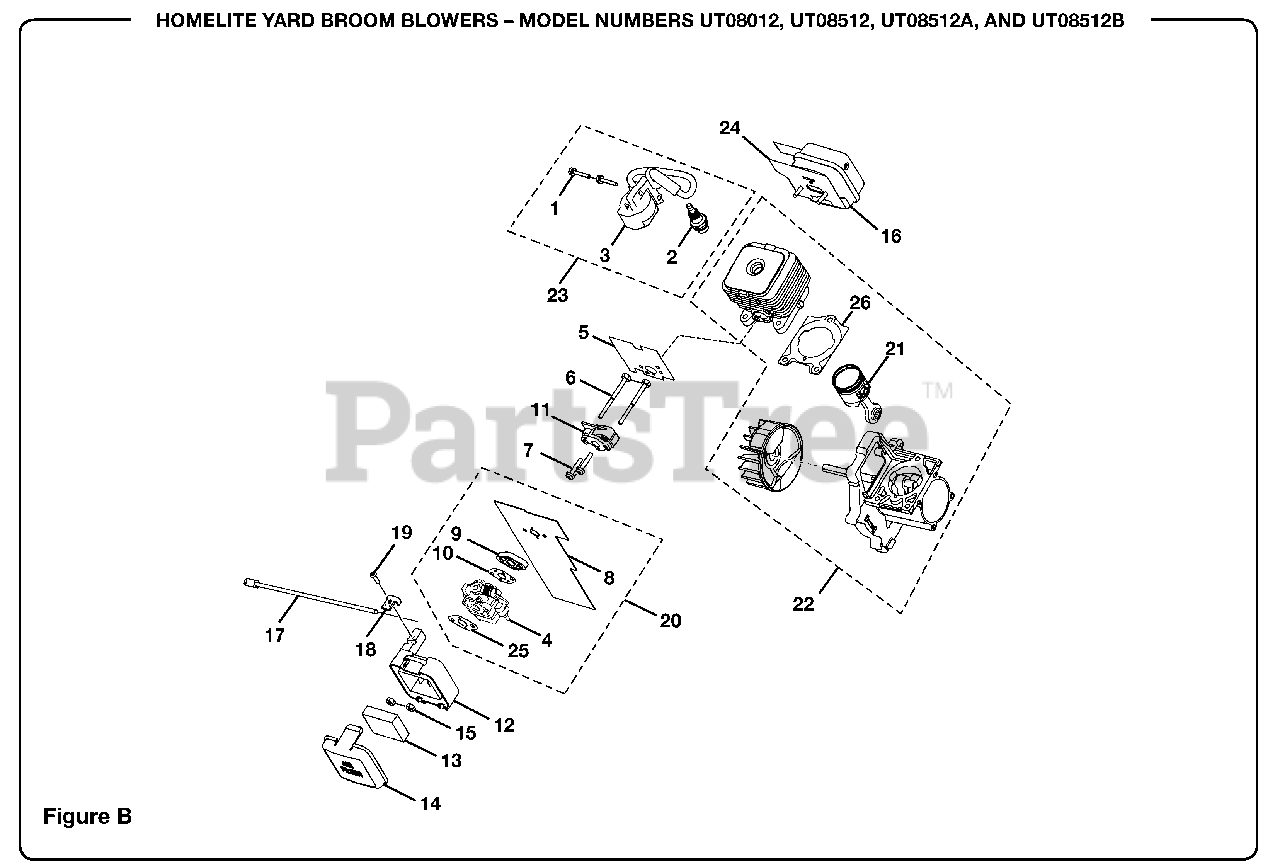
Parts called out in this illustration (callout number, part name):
1	SCREW THD FORMING
2	SPARK PLUG
3	IGNITION MODULE
4	CARBURETOR
5	HEAT DAM GASKET
6	CARBURETOR MOUNTING BOLT
7	SCREW (10-24 x 1.11 PAN HD.)
8	CARBURETOR GASKET
9	SPACER
10	GASKET
11	HEAT DAM
12	AIR FILTER BOX
13	AIR FILTER
14	AIR FILTER COVER
15	HEX NUT (10-24)
16	MUFFLER
17	THROTTLE CABLE
18	THROTTLE CABLE CLIP
19	SCREW-FILTER BOX
20	CARBURETOR KIT
21	PISTON ASSEMBLY KIT
22	SHORT BLOCK ASSEMBLY
23	IGNITION KIT
24	MUFFLER GASKET
26	CYLINDER GASKET
